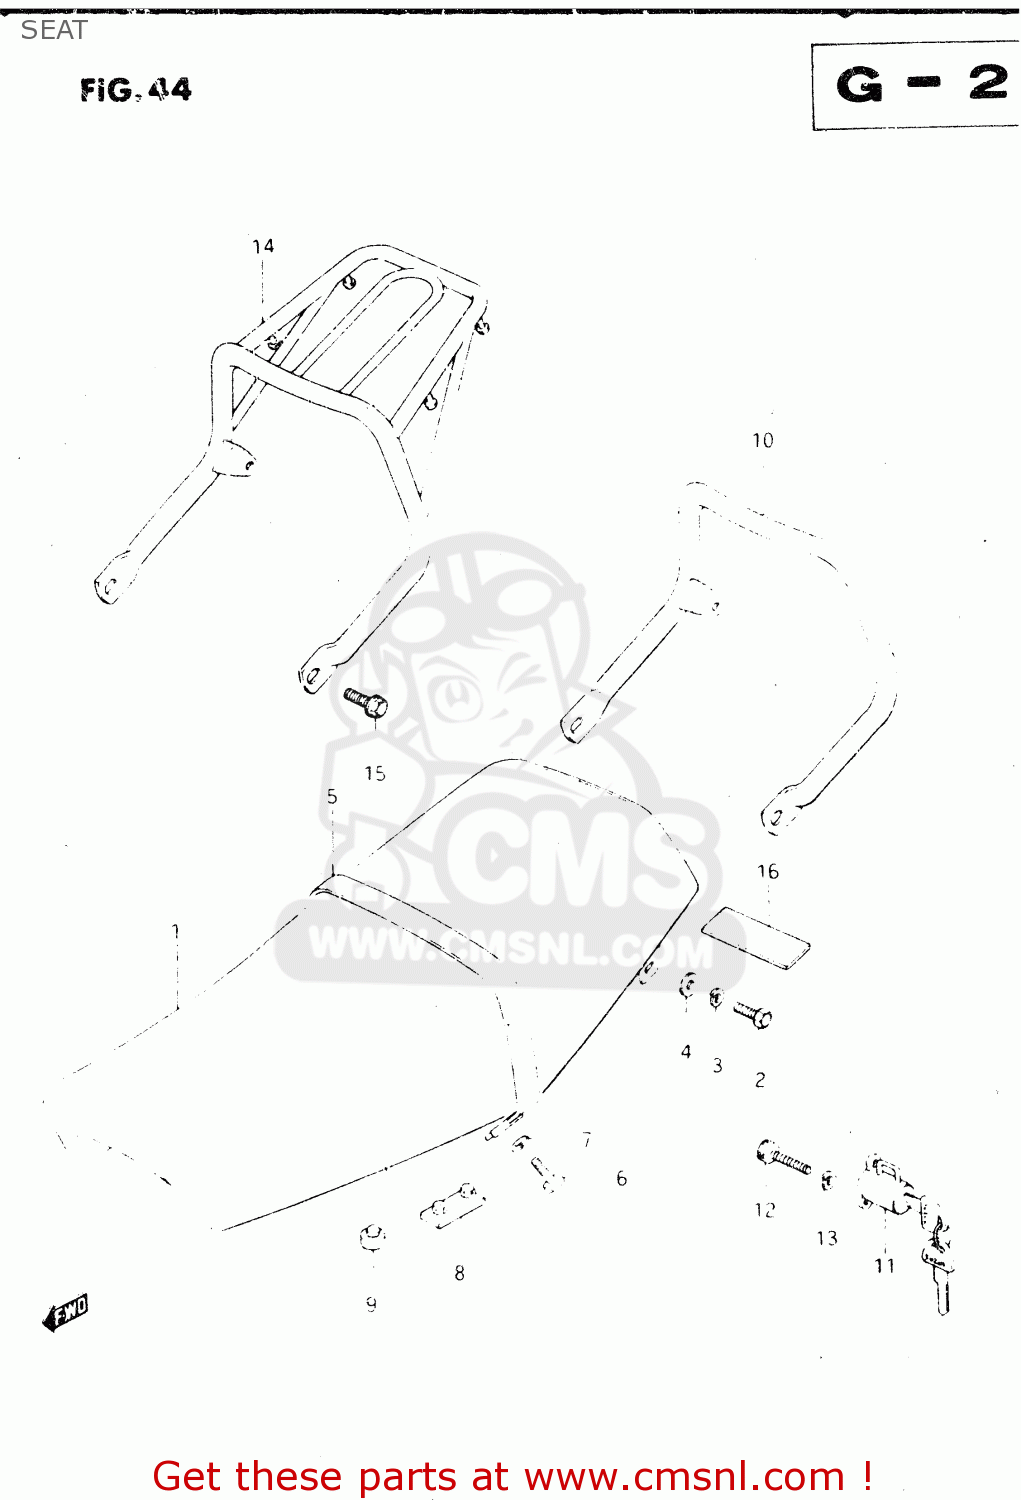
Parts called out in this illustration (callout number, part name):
1	SEAT ASSY (BLUE)
2	BOLT
3	LOCK WASHER
4	WASHER
5	BAND,SEAT GRIP
6	BOLT
7	LOCK WASHER
8	CUSHION
9	CUSHION
10	HANDLE, PILLION RIDER
11	LOCK ASSEMBLY,HELMET
12	BOLT 6X11
13	LOCK WASHER
14	CARRIER
15	BOLT
16	TAPE, SEAT UNDER
